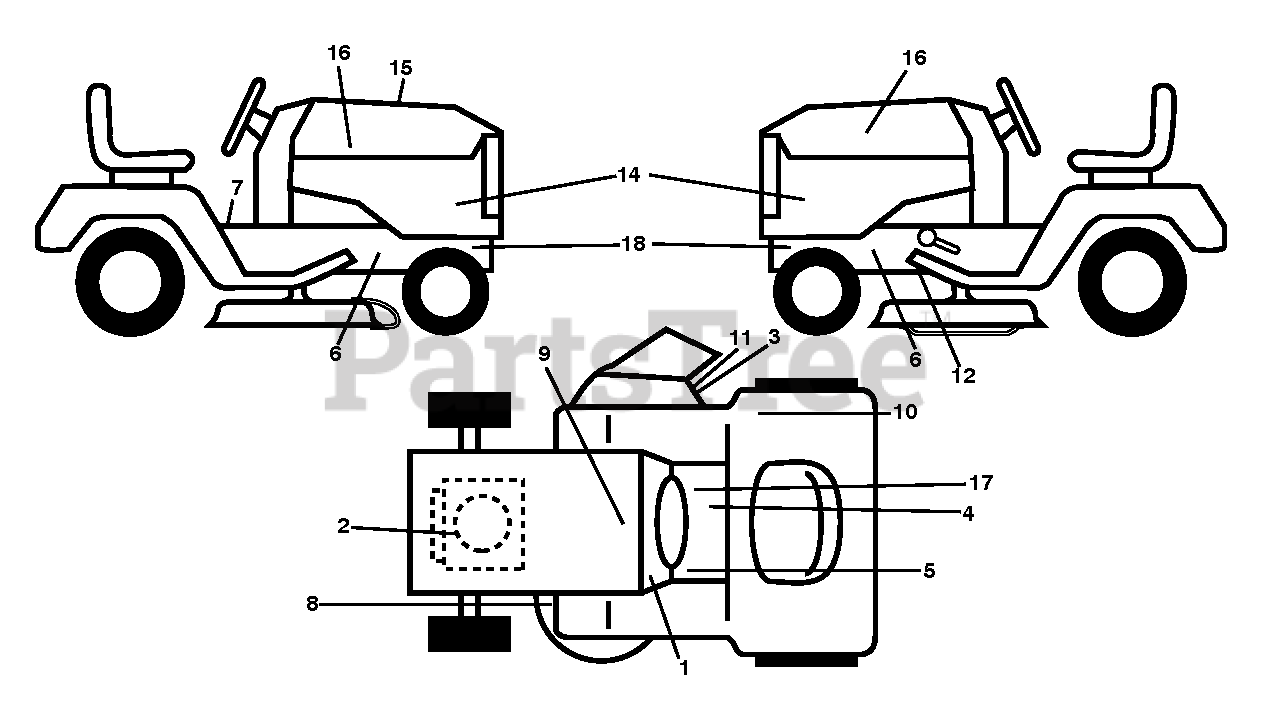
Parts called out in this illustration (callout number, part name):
1	DECAL.SNOWFLAKE.MS498.HUSQ
2	DECAL.ENG.BS.ENDUR.382022
3	DECAL.DFLCTR.WARNNG.CTFNGR.SYM
4	DECAL.PEDALS.SYMBOL
5	DECAL.FNDR.SDLE.BRAKE.CLUTCH.6
6	DECAL.WARNING.SERVCE/FIRE
7	DECAL.READ.OWN.MAN.SYMBOL.LT
8	DECAL.V-BELT.SCH.42/46"MEC/ELE
9	DECAL BTRY SYMBOLS
10	Decal, Certification 6MIL 100D
11	DECAL.CUTFINGER.CE.02
12	DECAL.PEDAL.HUSQ.CROWN
14	DCL.SDPNL.HUSQGT2.YTH224TFI.
15	DCL.RPL.BSM40.ENDUR.TLW.46.K57
16	DECAL.BADGE.170MM.TEXTLOGO.
17	DECAL.PARKING.BRAKE.SADDLE.LT
18	DECAL.CHASSIS.HOT.MUFFLER
